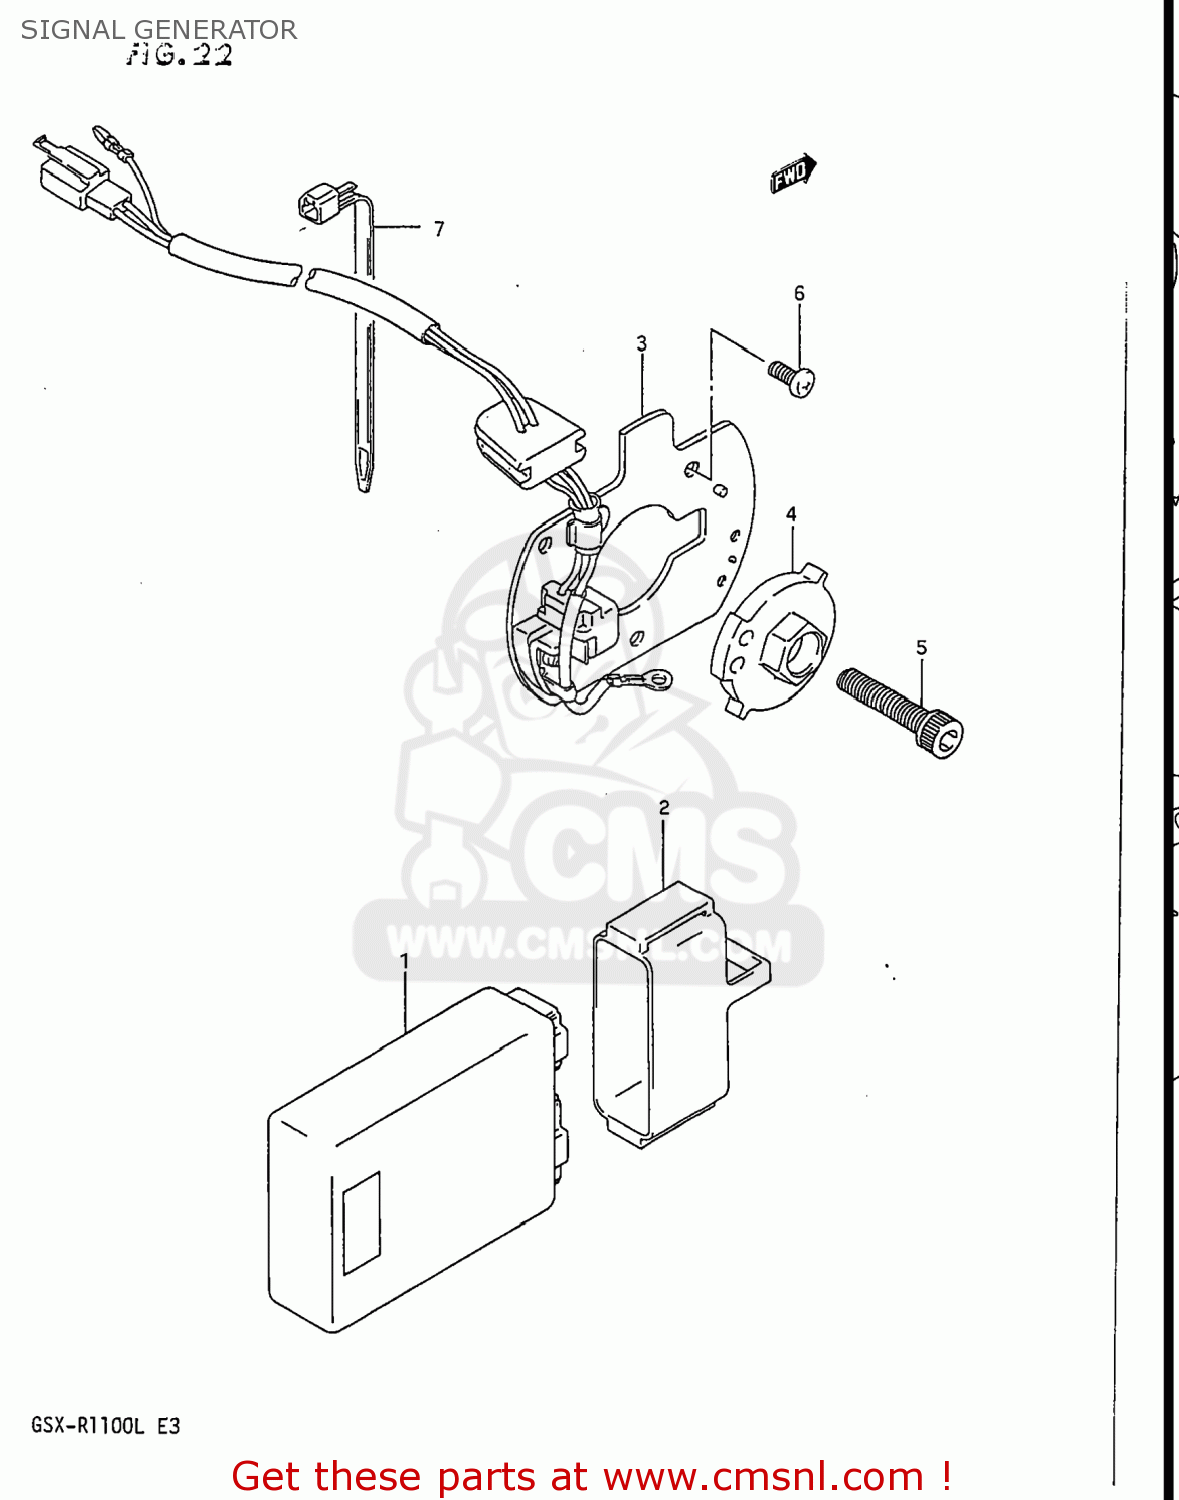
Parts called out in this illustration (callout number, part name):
1	IGNITOR
2	CUSHION,IGNITER
3	GENERATOR ASSY,SIGNAL
4	ROTOR,SIGNAL
5	BOLT
6	SCREW
7	CLAMP(L:125)
